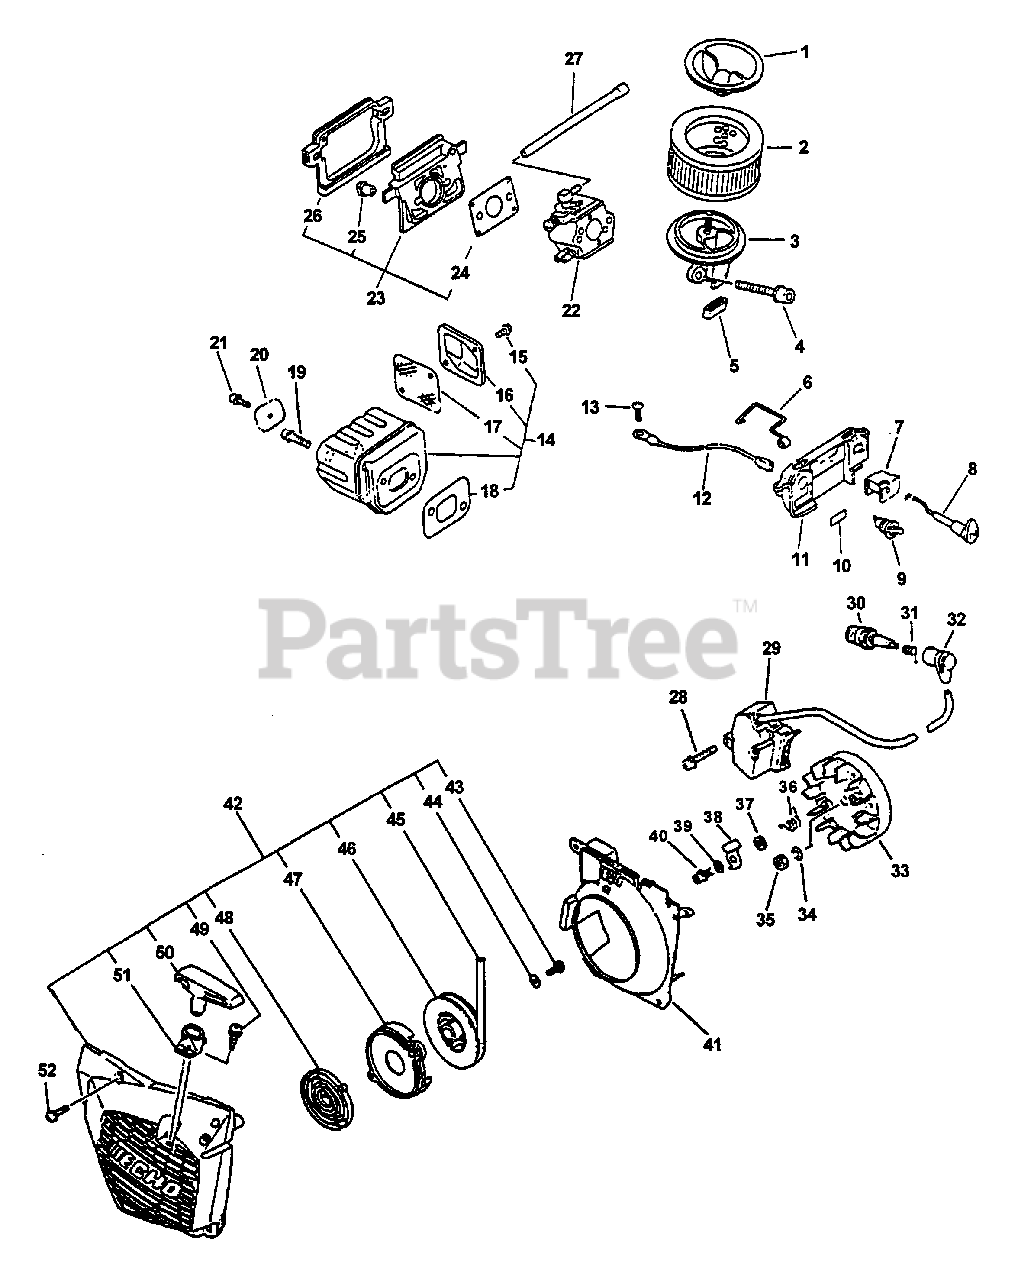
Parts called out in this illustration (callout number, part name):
1	COVER, AIR FILTER
2	FILTER, AIR
3	MOUNT, AIR FILTER
4	SCREW - 5X50
6	ROD, THROTTLE
8	ROD, CHOKE
9	IGNITION SWITCH ASSY
10	LABEL - STOP
11	BRACKET, SWITCH
12	LEAD - GROUND
13	SCREW - 4X6
14	MUFFLER ASSY
15	SCREW - 4X8
16	GUIDE, EXHAUST
17	SCREEN, SPARK ARRESTOR
18	GASKET, EXHAUST
19	SCREW - 5X14
20	PLATE
21	SCREW - 4X6
22	CARBURETOR WT-201A
23	INSULATOR KIT
24	GASKET, INTAKE
26	CUSHION
27	PIPE - IMPULSE
28	SCREW - 4X30
29	COIL, IGNITION
30	SPARK PLUG -- CJ-6Y
31	TERMINAL, SPARK PLUG CAP
32	CAP, SPARK PLUG
33	FLYWHEEL
34	LOCKWASHER - 8
36	SPRING, RETURN
38	PAWL, STARTER
39	WASHER - 5
40	SCREW - 5X14
41	SHIELD, FAN
42	STARTER ASSY
43	SCREW - 5X12
44	WASHER - 5
45	RePower BULK ROPE - 200 FEET
46	REEL, ROPE
47	PLATE, STARTER
48	SPRING, REWIND
49	SCREW - 3X14
50	GRIP, STARTER
51	GUIDE, ROPE
52	SCREW - 5X18
